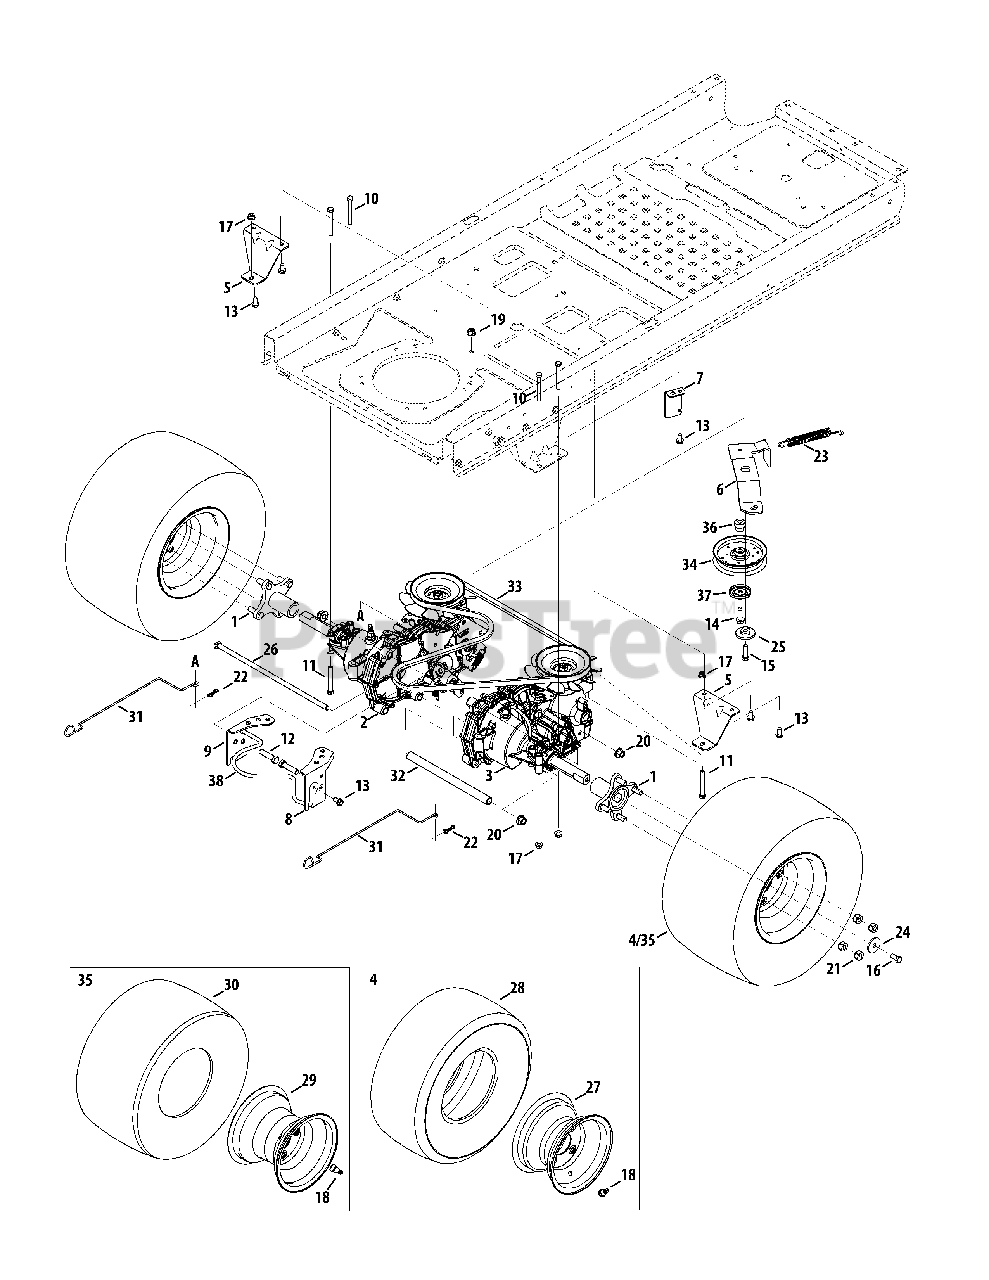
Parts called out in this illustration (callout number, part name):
1	Wheel Hub Assembly
2	Transmission Assembly, LH
3	Transmission Assembly, RH
4	Complete Wheel, 18 x 8.5-8 (42" & 46)
5	Transmission Mounting Bracket
6	Idler Bracket
7	Spring Mounting Bracket
8	Transmission Bracket
9	Transmission Bracket
10	Hex Screw, 5/16-18 x 2.75
11	Screw, TT, 5/16-18 x 2.25
12	Hex Screw, 7/16-20 x 1.75
13	Hex Washer Screw, 5/16-18 x .750
14	Hex Washer Screw, 3/8-16 x 1.250
15	Hex Screw, 3/8-16 x 1.00
16	Hex Screw, 3/8-16 x .75
17	Flange Lock Nut, 5/16-18
18	Valve Tubeless
19	Jam Lock Nut, 3/8-16
20	Flange Lock Nut, 7/16-20
21	Lug Nut, 7/16-14
22	Bow-Tie Cotter Pin
23	Extension Spring, .75 Dia. x 6.02
24	Flat Washer, .390 x 1.50 x .134
25	Shoulder Spacer, .884 x .190
26	Rod, .405 Dia. x 14.0 LG
27	Rim Only, (42" & 26")
28	Tire Only, 18 x 8.5-8 (42" & 46")
29	Rim Only, (50" & 54")
30	Tire Only, 18 x 9.5-8 (50" & 54")
31	Bypass Rod
32	Tube, .51 ID x .75 OD x 10.2
33	Belt, A-Type x 67.0
34	Idler Pulley, 4.25 Dia.
35	Complete Wheel, 18 x 9.5-8 (50" & 54")
36	Shoulder Spacer
37	Pulley Cap
38	Engine Keeper Rod (46", 50" & 54")
